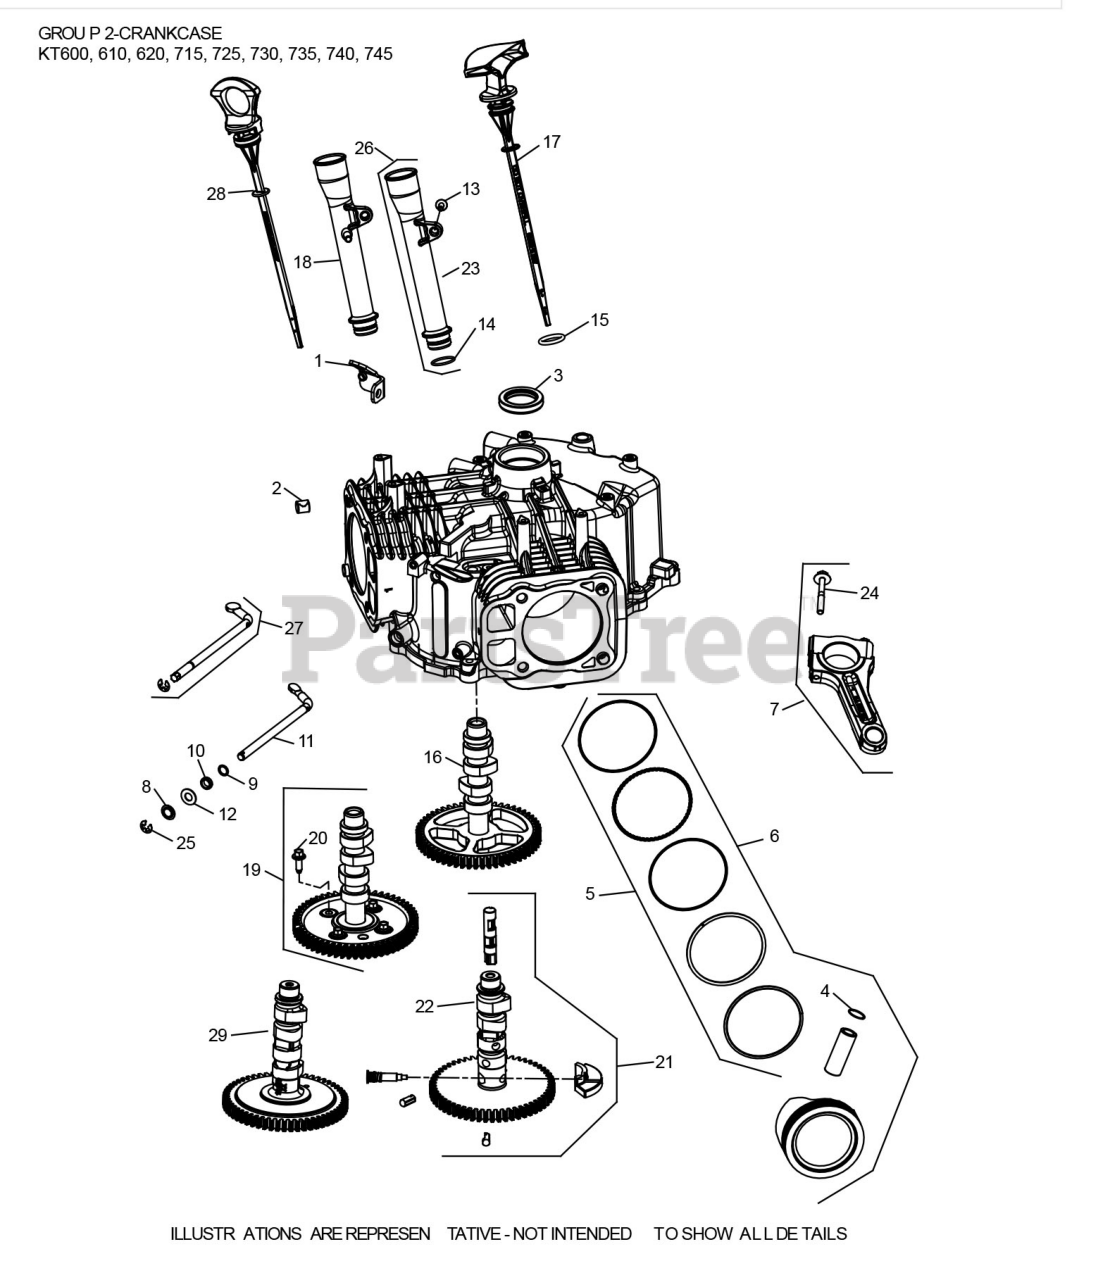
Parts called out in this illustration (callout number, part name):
1	BRACKET-OIL FILL TUBE
2	PIN-SPLIT DOWEL
4	RETAINER-PISTON
6	PISTON KIT (STD)
7	CONNECTING ROD ASSEMBLY
9	WASHER-1/4 FLAT
12	WASHER-9MM FLAT
15	O-RING DIPSTICK
16	CAMSHAFT ASSEMBLY
18	DIPSTICK TUBE
25	GOVERNOR SHAFT RETAINER CLIP
27	CROSS CARBURETOR SHAFT KIT
